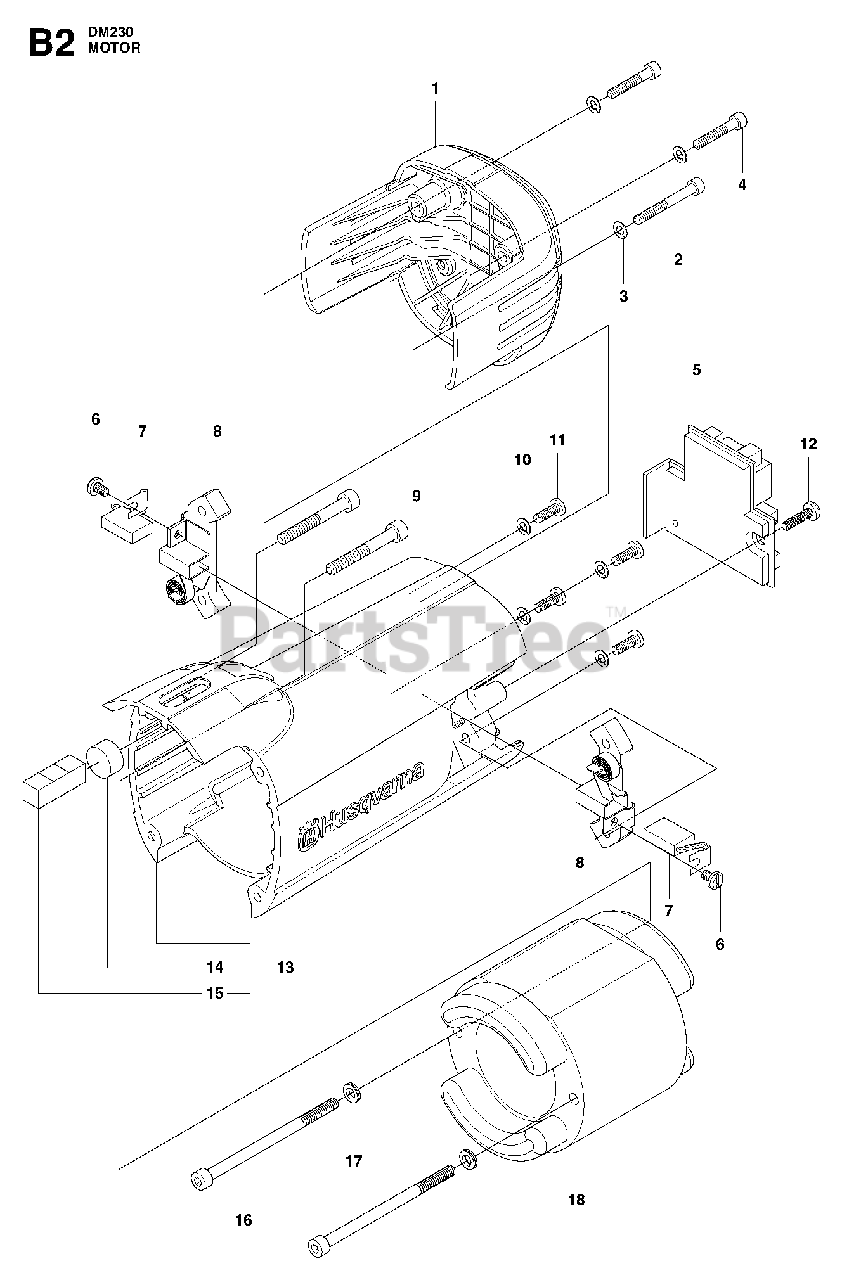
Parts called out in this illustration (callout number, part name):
2	SCREW IHSCFM
3	SPRING WASHER
4	SCREW IHSCFM
5	PRINTED CIRCUIT ASSY110 V
5	PRINTED CIRCUIT ASSY230 V
6	SCREW SLPANM
9	SCREW IHSCM
10	SPRING WASHER
13	MOTOR HOUSINGIncl. 14 - 15
